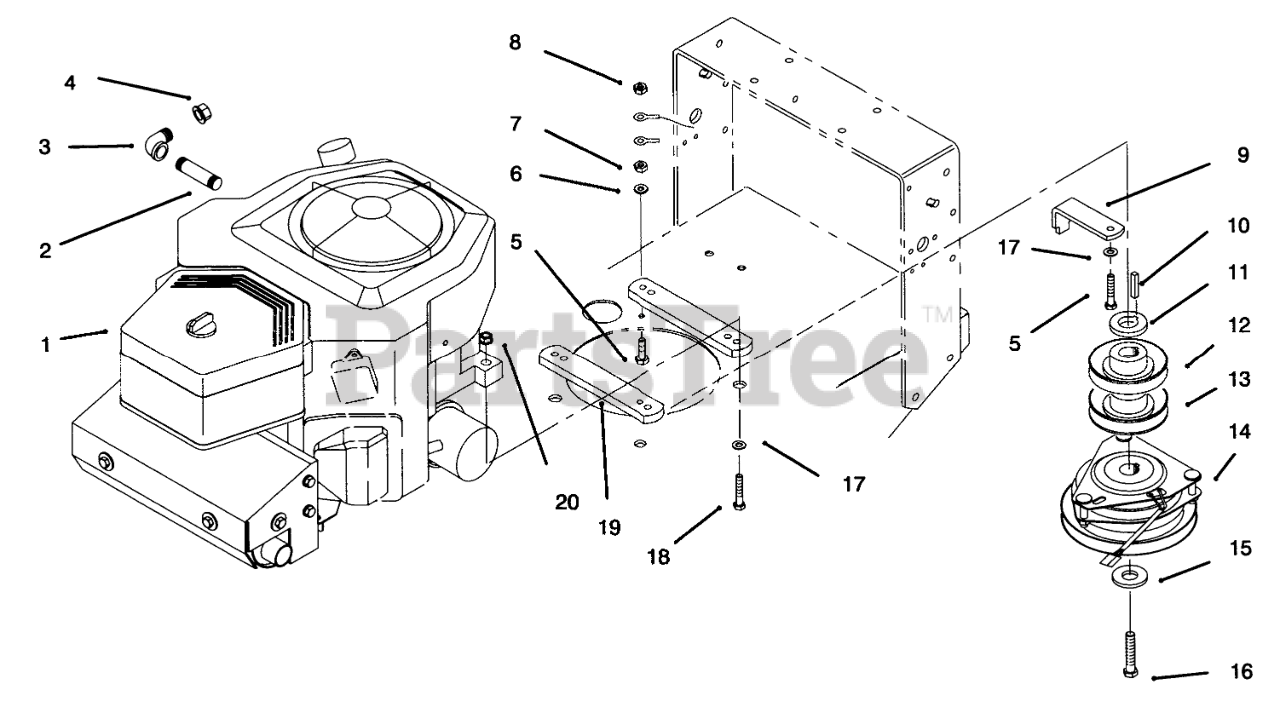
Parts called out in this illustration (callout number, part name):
1	ENGINE - 18 HP KOHLER
2	NIPPLE
3	ELBOW-STREET, 90 DEG
4	CAP-PIPE
5	SCREW-HH
6	WASHER-LOCK
7	NUT-HEX, SIDE DEFORM
8	NUT-KEPS
9	Retainer-Clutch
11	SPACER - PULLEY
12	SHEAVE-UPPER HALF
13	SHEAVE-LOWER HALF
14	CLUTCH/BRAKE
15	WASHER
16	SCREW-HH
17	WASHER-PLAIN
18	SCREW-HH
19	SPACER - ENGINE
20	NUT-LOCK, CONE
